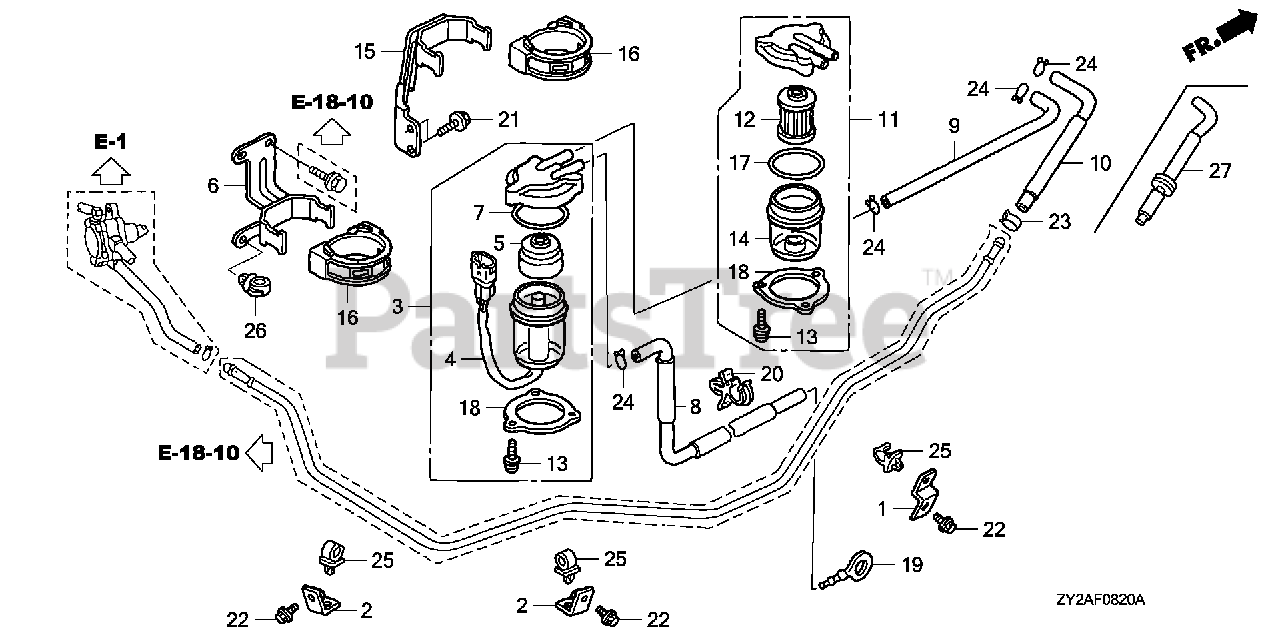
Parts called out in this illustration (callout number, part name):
1	STAY, FUEL PIPE A
2	STAY, FUEL PIPE B
3	SEPARATOR ASSY., WATER
4	CUP, WATER SEPARATOR
5	BUFFER, PLATE
6	STAY, WATER SEPARATOR
8	TUBE, FUEL (A)
9	TUBE, FUEL (B)
10	TUBE, FUEL (C)
11	FILTER, FUEL
12	FILTER, FUEL
13	SCREW, PAN (5X12)
14	CUP, FUEL STRAINER
15	STAY, FUEL STRAINER
16	SUSPENSION, STRAINER
19	PLUG, FUEL TUBE
20	HOLDER, ROD (A)
21	BOLT, FLANGE (6X14)
22	BOLT, FLANGE (6X12)
23	CLAMP, TUBE (D12)
24	CLIP, TUBE (B12)
25	CLAMP, WIRE (8MM)
26	CLIP, WIRE HARNESS (25MM)
27	TUBE, FUEL (C)
